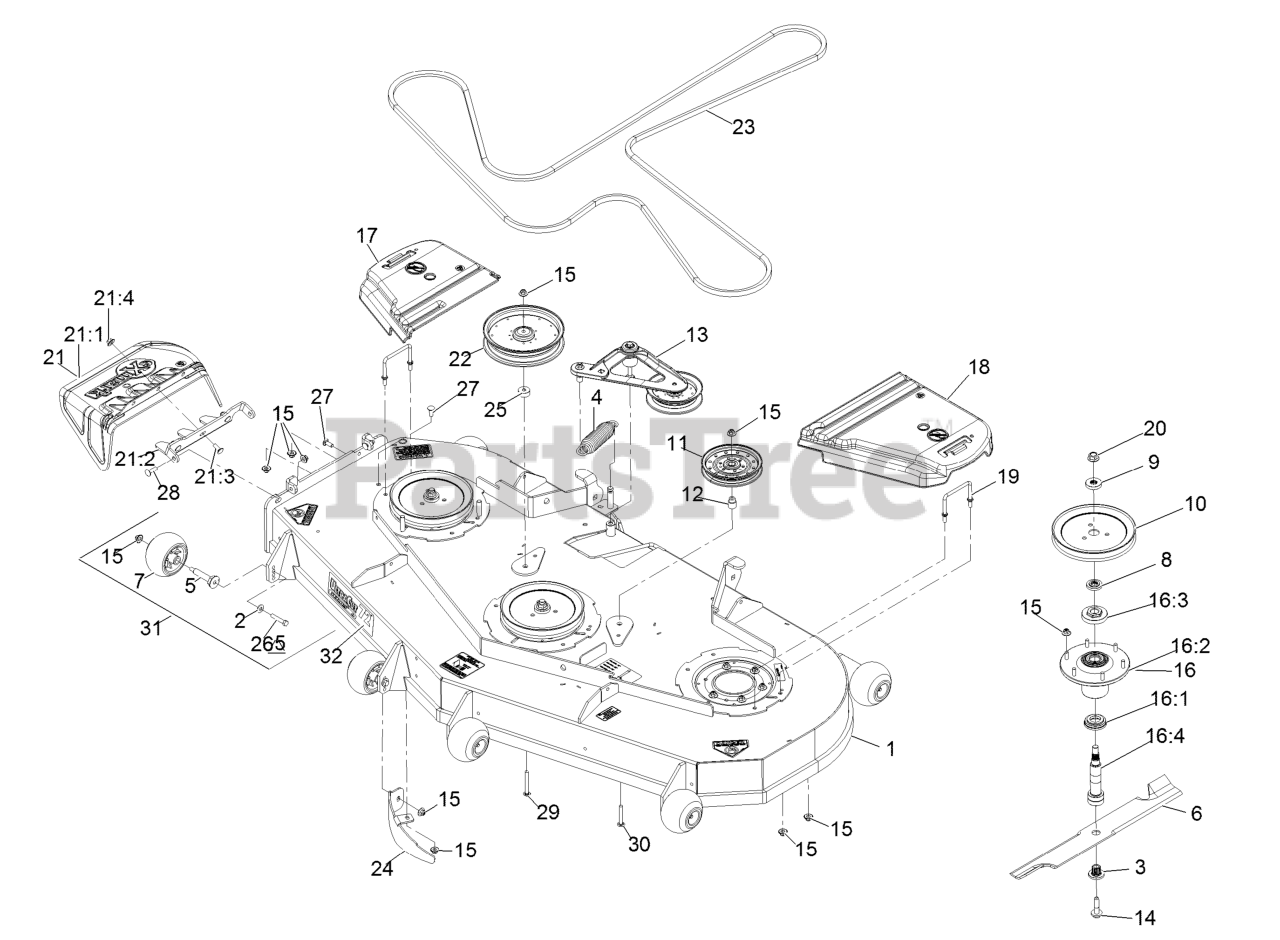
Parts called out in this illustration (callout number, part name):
1	DECK W/ DECALS ASM-72
2	WASHER-BELLEVILLE
3	BUSHING,SPLINED
4	SPRING-EXTENSION
7	ROLLER-SCALP, ANTI
8	SPACER,SPLINED STEPPED
9	SPACER,SPLINED
10	SHEAVE,BLADE DRIVE 9.00
12	BUSHING-IDLER
13	DECK IDLER ASM
14	SCREW,SEMS 1/2-20 X 2.19
15	Nut-Nyloc 3/8-16 Flg
16	ASM,SPINDLE HOUSING
16:1	GUARD,BOTTOM
16:2	ASM,CUTTER HOUSING
16:3	NUT, SPINDLE 7/8-14
16:4	SPINDLE,DOUBLE SPLINE
17	COVER-BELT, RH
18	COVER-BELT, LH
19	WIREFORM-COVER
20	NUT-FLANGE, CENTERLOCK
21	ASM,DISCHARGE CHUTE
21:1	CHUTE,DISCHARGE
21:2	BRACKET,DISCHARGE CHUTE
21:3	SCREW-CARR
21:4	Nut-Nyloc 3/8-16 Flg
22	PULLEY-IDLER
23	BELT-V
24	BAFFLE-DOGLEG, LZ72
25	SPACER-IDLER
26	SCREW-HH
27	SCREW-CARR
28	Bolt-Carriage 3/8-16 X 1 1/4
29	SCREW-CARR
30	SCREW-CARR
32	DECAL,ULTRACUT 72 SERIES
